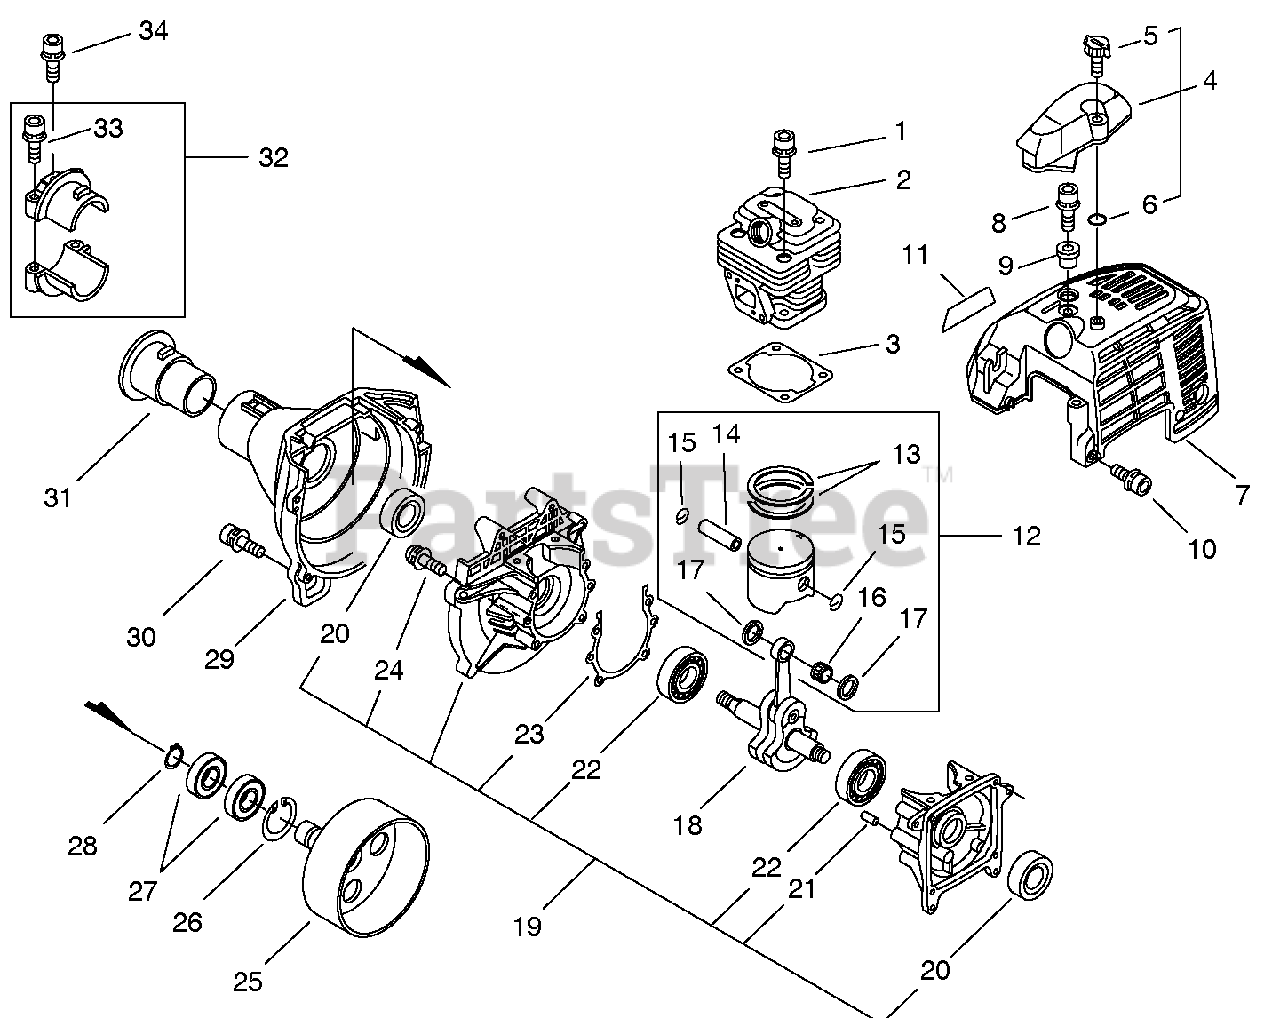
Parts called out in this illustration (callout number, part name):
1	BOLT 5×20
2	CYLINDER
3	GASKET, CYLINDER
4	GUARD KIT, TOP
5	THUMBSCREW M5×15.5
7	COVER, ENGINE
8	BOLT 5×20
10	BOLT 5×12
11	LABEL, ECHO SRM-3605
12	PISTON KIT
13	RING, PISTON
14	PIN, PISTON
15	RING, SNAP
16	BEARING, NEEDLE 9
17	WASHER, THRUST
18	CRANKSHAFT ASSY
19	CRANKCASE KIT
20	SEAL, OIL 12
21	PIN, LOCATING 4×8
22	BEARING, BALL - 6201 C3
23	GASKET, CRANKCASE
24	BOLT 5×30
25	DRUM, CLUTCH
26	RING, SNAP 28
27	BEARING, BALL 6001
28	RING, RETAINING - 12
29	COVER, FAN
30	BOLT 5×20
31	CUSHION 28
32	HOLDER KIT
33	BOLT 5×25
34	BOLT 5×12
